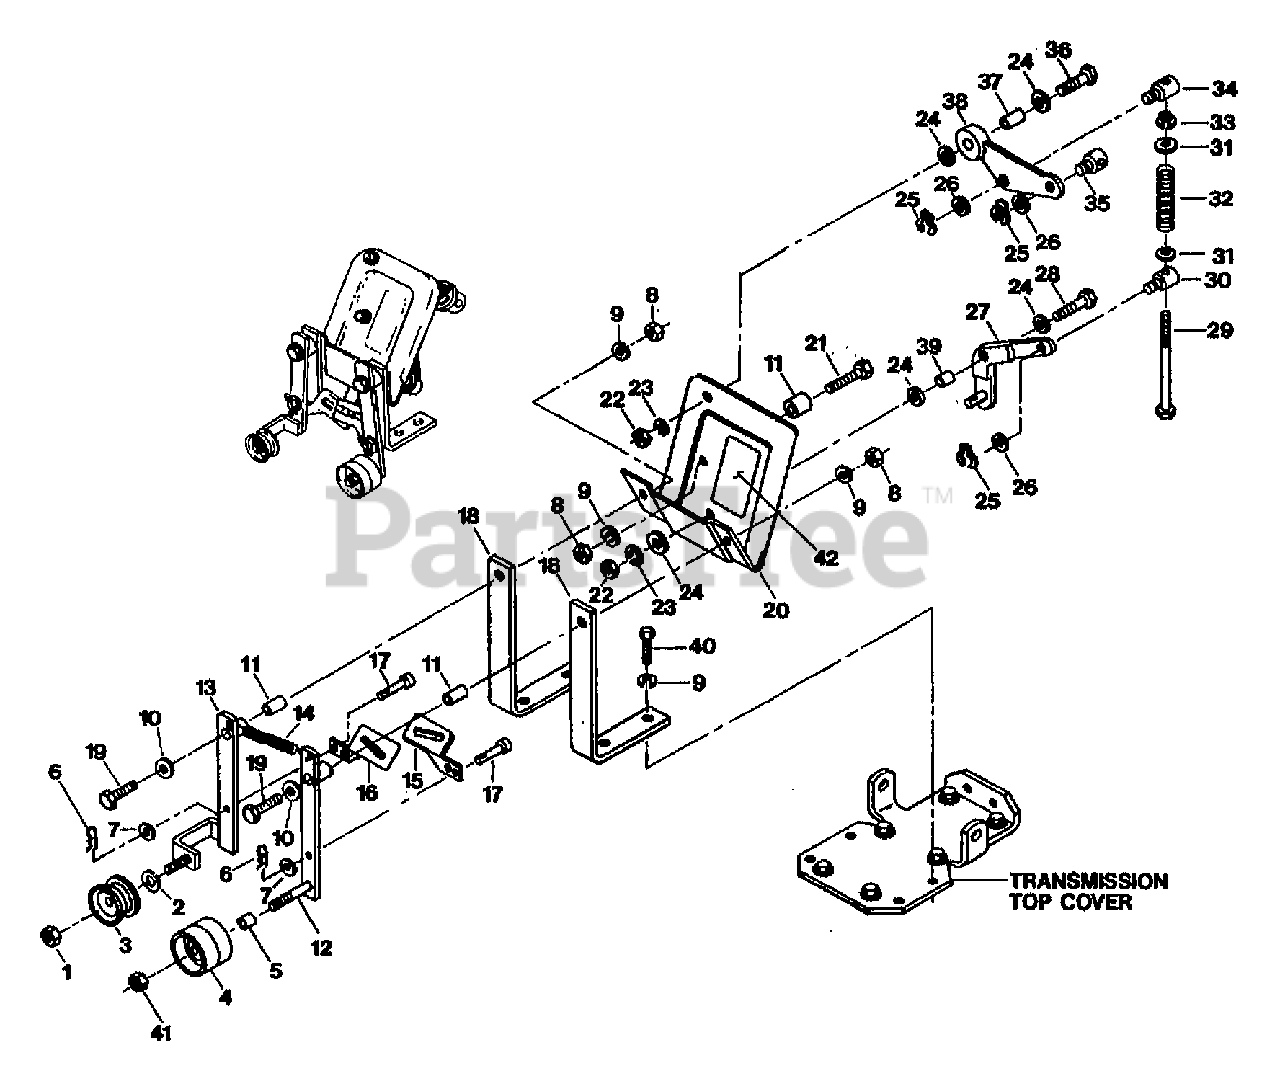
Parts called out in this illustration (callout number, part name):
1	NUT-LOCK 3/8-16 NYLON ZP
2	BUSHING-.54X.38X.08
3	IDLER-REV
4	PULLEY-FWD IDLER
5	BUSHING-.5X.375X.3
6	PIN-CLIP .08
7	WASHER-FLAT 1/4 SAE
8	NUT-HEX 5/16-18 ZP
9	WASHER-LK .312 ZP
10	WASHER-#.75X.32X.09 ZP
11	BUSHING-.438X.323X.712
12	ARM-IDLER FWD PNT
13	IDLER-REV
14	SPRING-.436 X 3.25
15	LINK-FWD
17	PIN-CLEVIS .375X.719 ZP
18	MOUNT BAR-PNT (20691)
19	BOLT-HH 5/16-18 X 2 G5 ZP
20	BASE-SHIFTING W/DECAL (INCL. #50112 WARNING DECAL)
21	SCR-HH 5/16-18X1.25 G5ZP
22	NUT-HEX 3/8-16 ZP
23	WASHER-LK .375 @ DEPL
24	SPACER-.88X.385X.09 ZP
25	RING-KLIP .500 ZINC
26	WASHER-#.88X.51X.063 ZP
27	BELLCRANK-WELDMENT
28	SCR-HH 3/8-16X1.25
29	SCR-HH 1/4-20X4.5 G5
30	PIVOT-SLIDE
31	WASHER ZP
32	SPRING-.52 X 3
33	RING-KLIP 5304-25
34	PIVOT-THREADED
35	PIVOT-ROD (FORWARD/NEUTRAL/REVERSE LEVER)
36	BOLT-HH 3/8-16X1.5 FTH ZP
37	BUSHING-.5X.38X.665
38	RODCRANK
39	BUSHING-.5X.38X.4
40	SCR-HH 5/16-18X1.0 G5 ZP
41	NUT-H/LK 3/8-16
42	DECAL-BELT WARNING (WARNS ABOUT MOVING BELTS AND PULLEYS)
